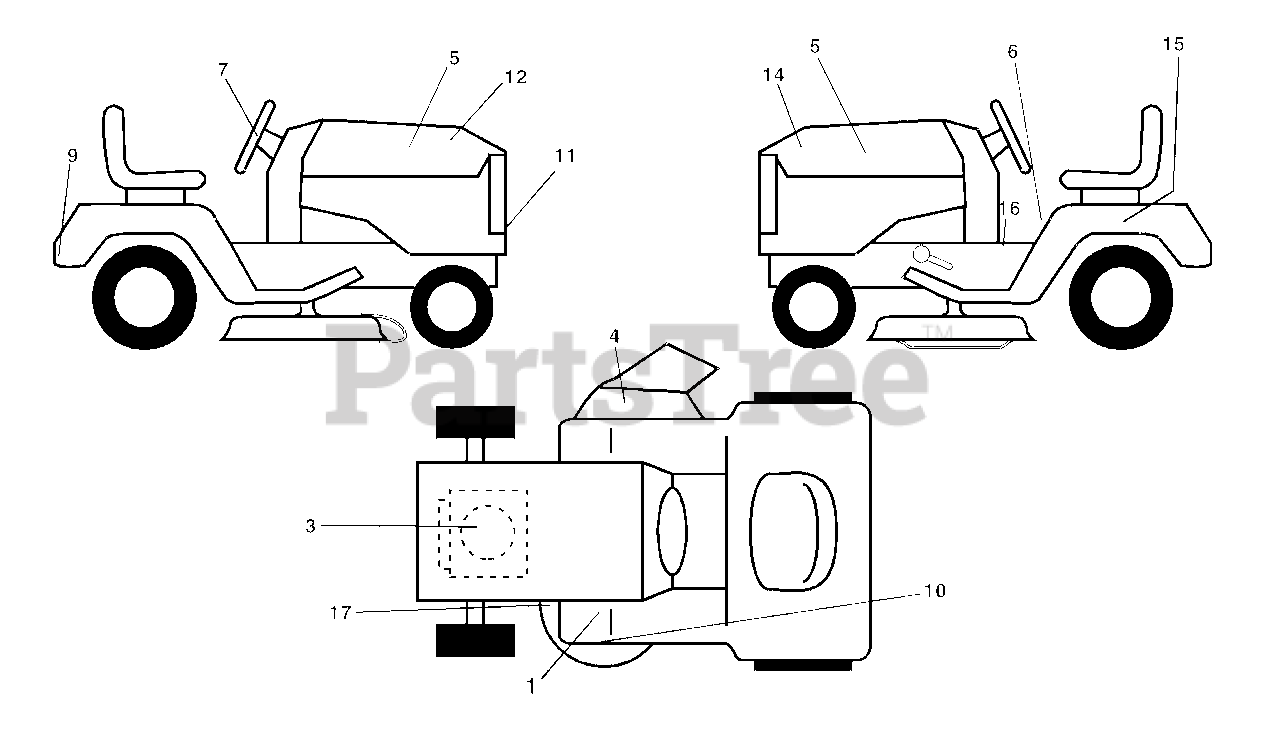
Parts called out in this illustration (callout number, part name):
1	Decal, Clutch/Brake Eng/Fr
3	Decal, Engine HP
4	Decal Warning
5	Decal, Pnl Sd
6	Decal, Fender Danger English
7	Decal Ins Str Wh
9	Decal Fender
10	Decal, Deck Grasseater
11	Decal, Grille Weedeater
12	Decal, Hood RH
14	Decal, Hood LH
15	Decal, Caution, Battery
16	Decal, Oper Sdl P/L Gear Dr Eng
17	Decal, V-Belt Sch.
